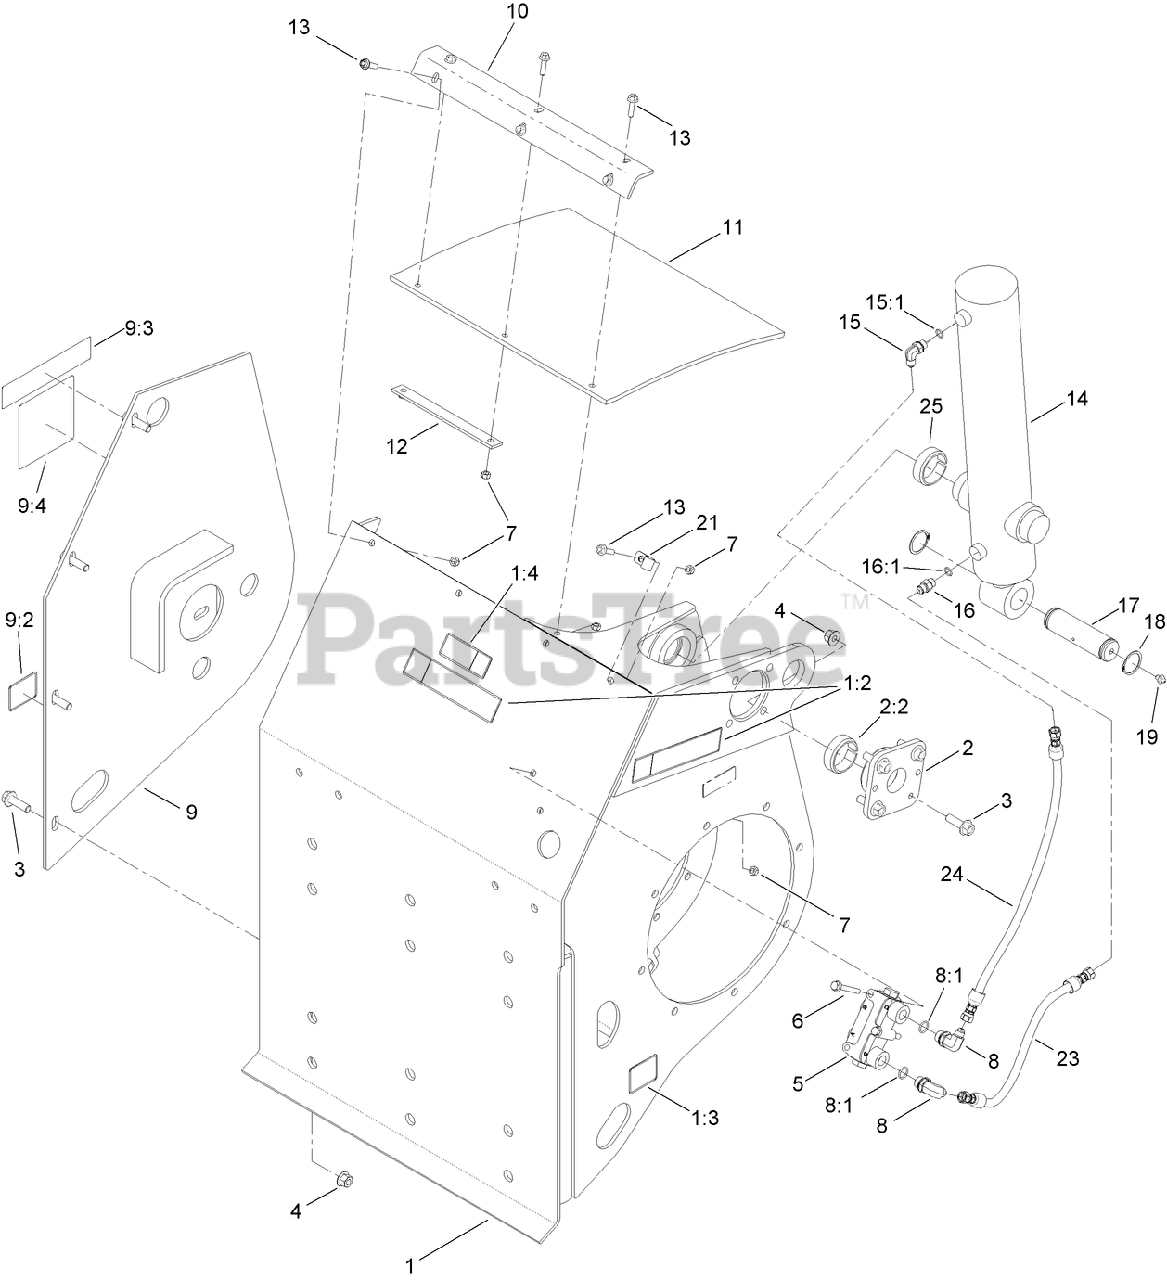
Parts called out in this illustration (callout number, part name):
1	FRAME-TRENCHER
1:2	DECAL-DANGER, ENTANGLEMENT
1:3	DECAL-TIE DOWN
1:4	DECAL-DANGER
2	PIVOT BLOCK ASM
2:2	BUSHING
4	NUT-LOCK, HHF
5	HYD LOCKOUT VALVE ASM
6	SCREW-HHF
7	NUT-LOCK, NI
8	FITTING-ELBOW, 90 DEG
8:1	O-RING
9	SUPPORT-BEARING
9:2	DECAL-TIE DOWN
9:3	DECAL-DANGER, ENTANGLEMENT
9:4	DECAL-TRANSMISSION FLUID
10	ANGLE-DIRT DEFLECTOR
11	DEFLECTOR-DIRT
12	STRIP-DIRT DEFLECTOR
13	SCREW-HHF
14	CYLINDER-BOOM LIFT
15	FITTING-ELBOW, 90 DEG
15:1	O-RING
16	FITTING-STRAIGHT
16:1	O-RING
17	PIN-PIVOT
18	RING-RETAINING, EXTERNAL
19	FITTING-GREASE
23	HOSE ASM
24	HOSE ASM
25	BUSHING
